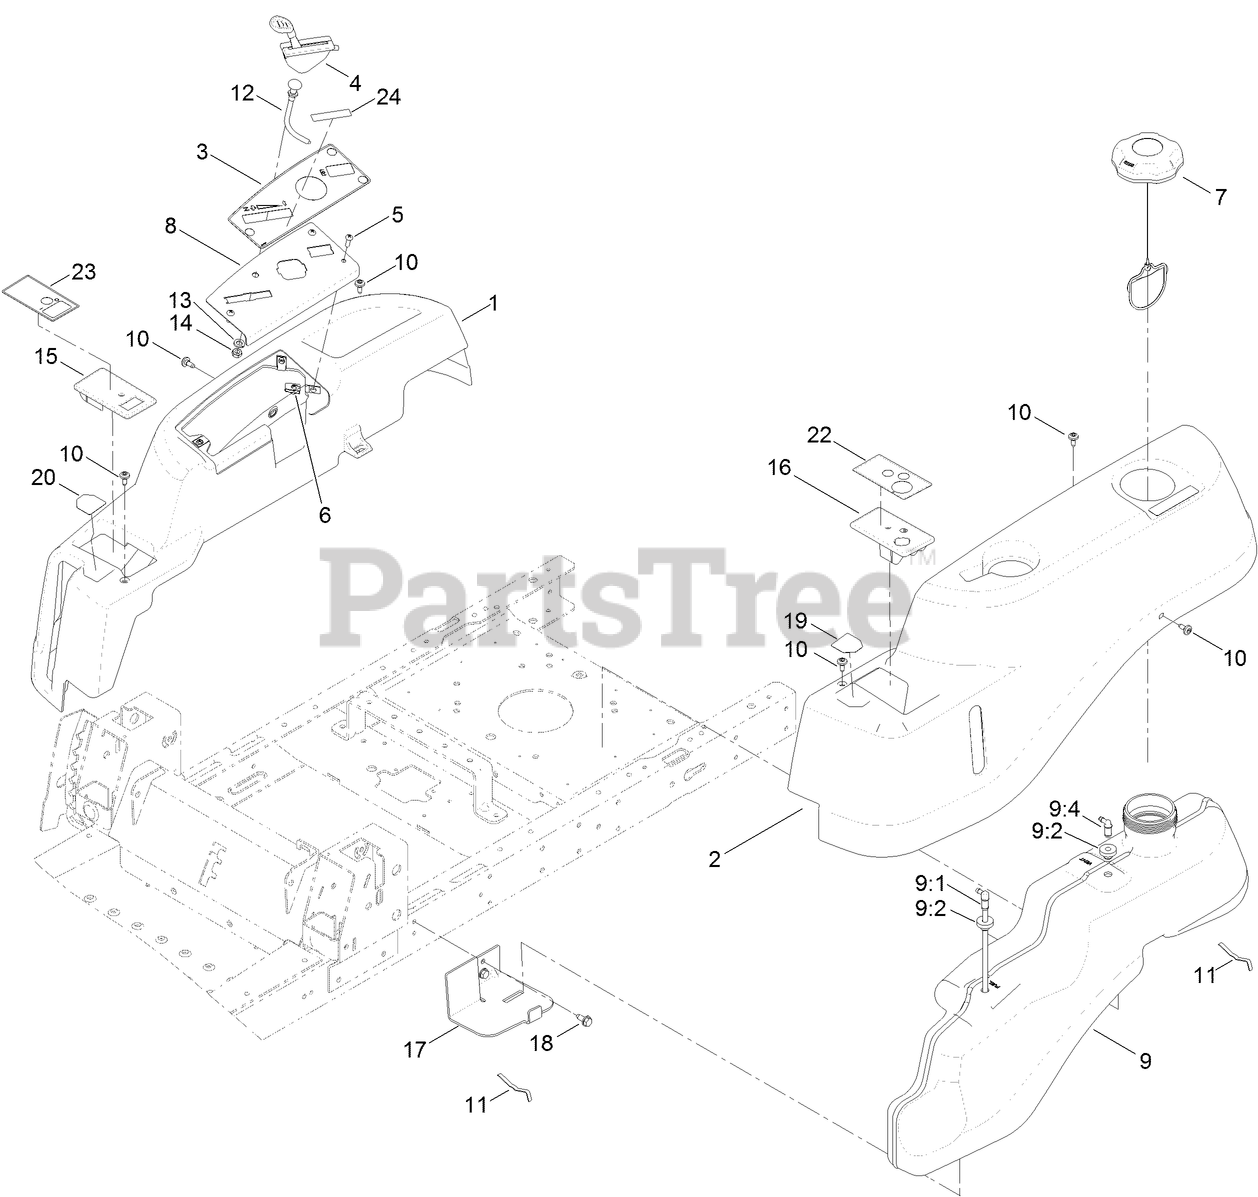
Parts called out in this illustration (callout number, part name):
1	POD-RH
3	DECAL-PANEL, CONTROL
4	CABLE-THROTTLE
5	SCREW-PRH
8	PLATE-CONTROL
9	FUEL TANK ASM
9:1	CONNECTOR-ELBOW, 90 DEG
9:2	BUSHING
9:4	FITTING-PLASTIC
10	SCREW-SHOULDER
11	SPRING
12	CABLE-CHOKE
13	WASHER-LOCK
14	NUT-HJ
15	COVER-RH
16	COVER-LH
17	SUPPORT-TANK, FRONT
18	SCREW-HWHTF
19	DECAL-NMIR
20	DECAL-CONTROL, PEDAL
22	DECAL-KEYCHOICE
23	DECAL-BRAKE, PARKING
24	DECAL-SHUTDOWN
